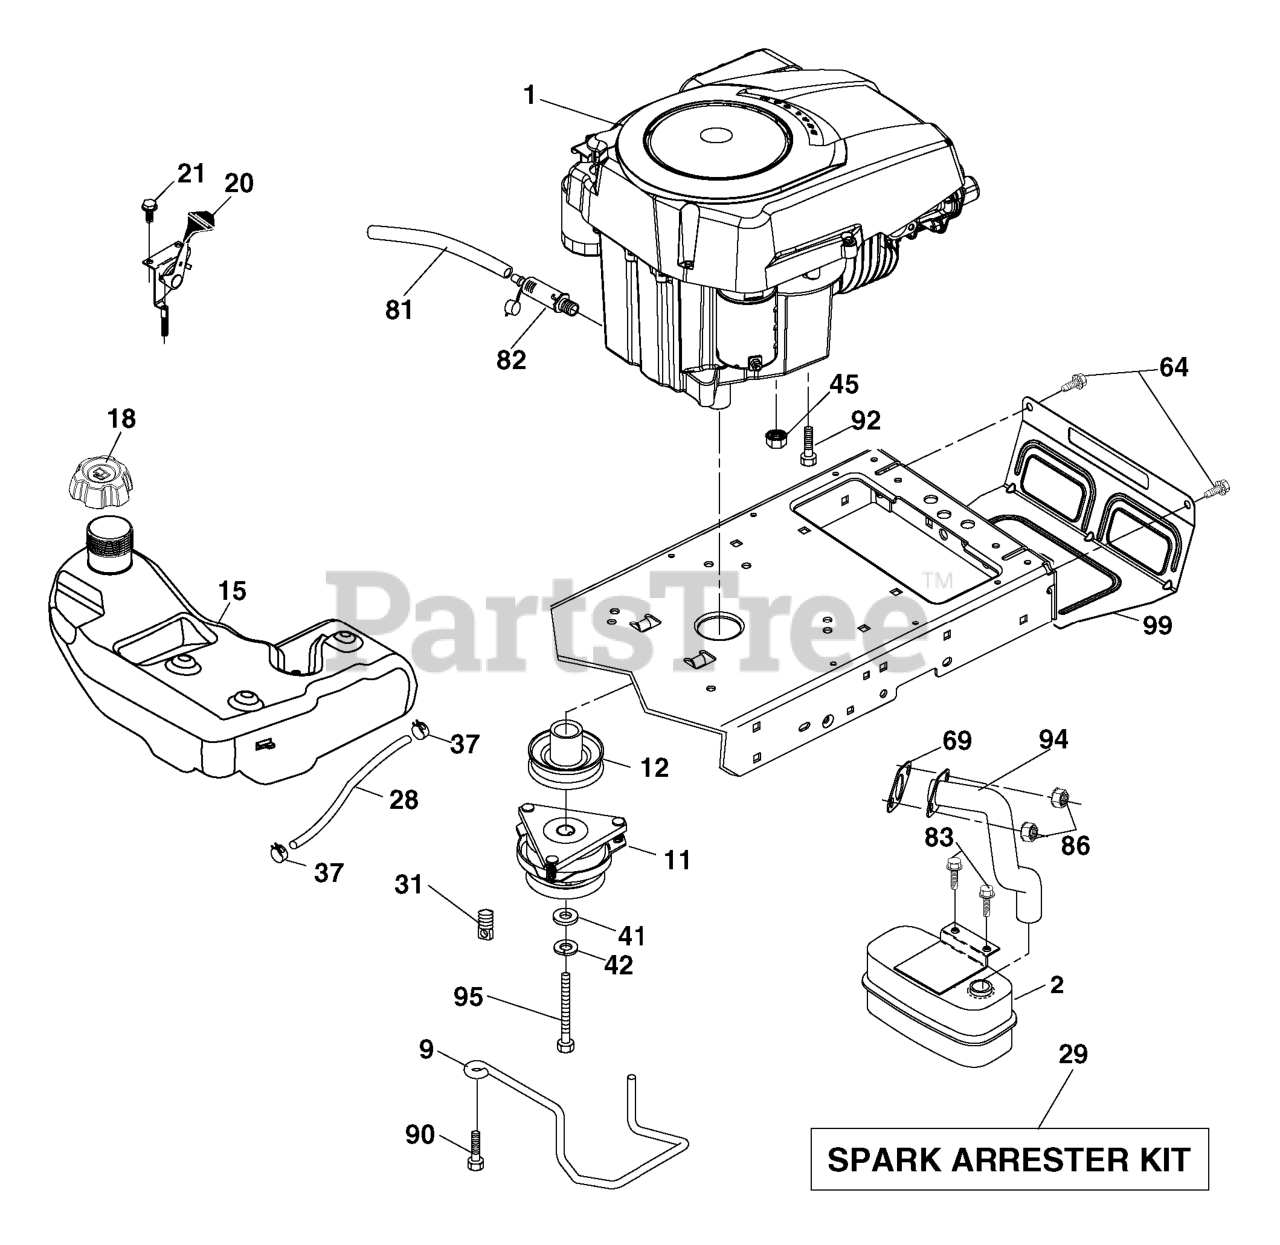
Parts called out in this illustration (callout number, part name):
2	MUFFLER.SINGLE.CYL.KOHL/B&S
9	KEEPER.BELT.ENGINE.4.2
11	RB.CLUTCH.OGURA.4.4.PD
12	PULLEY.ENGINE.TUFFTORQ
15	TANK.FUEL.4GAL
18	CAP.FUEL.TANK.3"GREY
20	CONTROL.TH/CK.COBRA.KO
21	SCREW
28	LINE.FUEL.64"REAR.EMIS
29	KIT.SPARK ARRESTOR 794945 B&S
31	DECAL BTRY SYMBOLS
37	HOSE CLAMP
42	LOCKWASHER
45	NUT
64	SCREW, 3/8-16X3/4
69	GASKET.EXHAUST.KOHLER
81	TUBE, DRAIN OIL ASM.
82	PLUG DRAIN OIL EASY
83	BOLT.5/16-18UNCX3/4 W/SEMS.BLK
86	NUT.HEX.FLANGE.TOPLOCK
90	SCREW 3/8-16X1
92	SCREW 3/8-16X1
94	RP.TUBE.EXHAUST.KOHL.COURAGE
95	BOLT HEX 7/16-20X4-1/4"
99	SHIELD.BROWNING/DEBRIS
